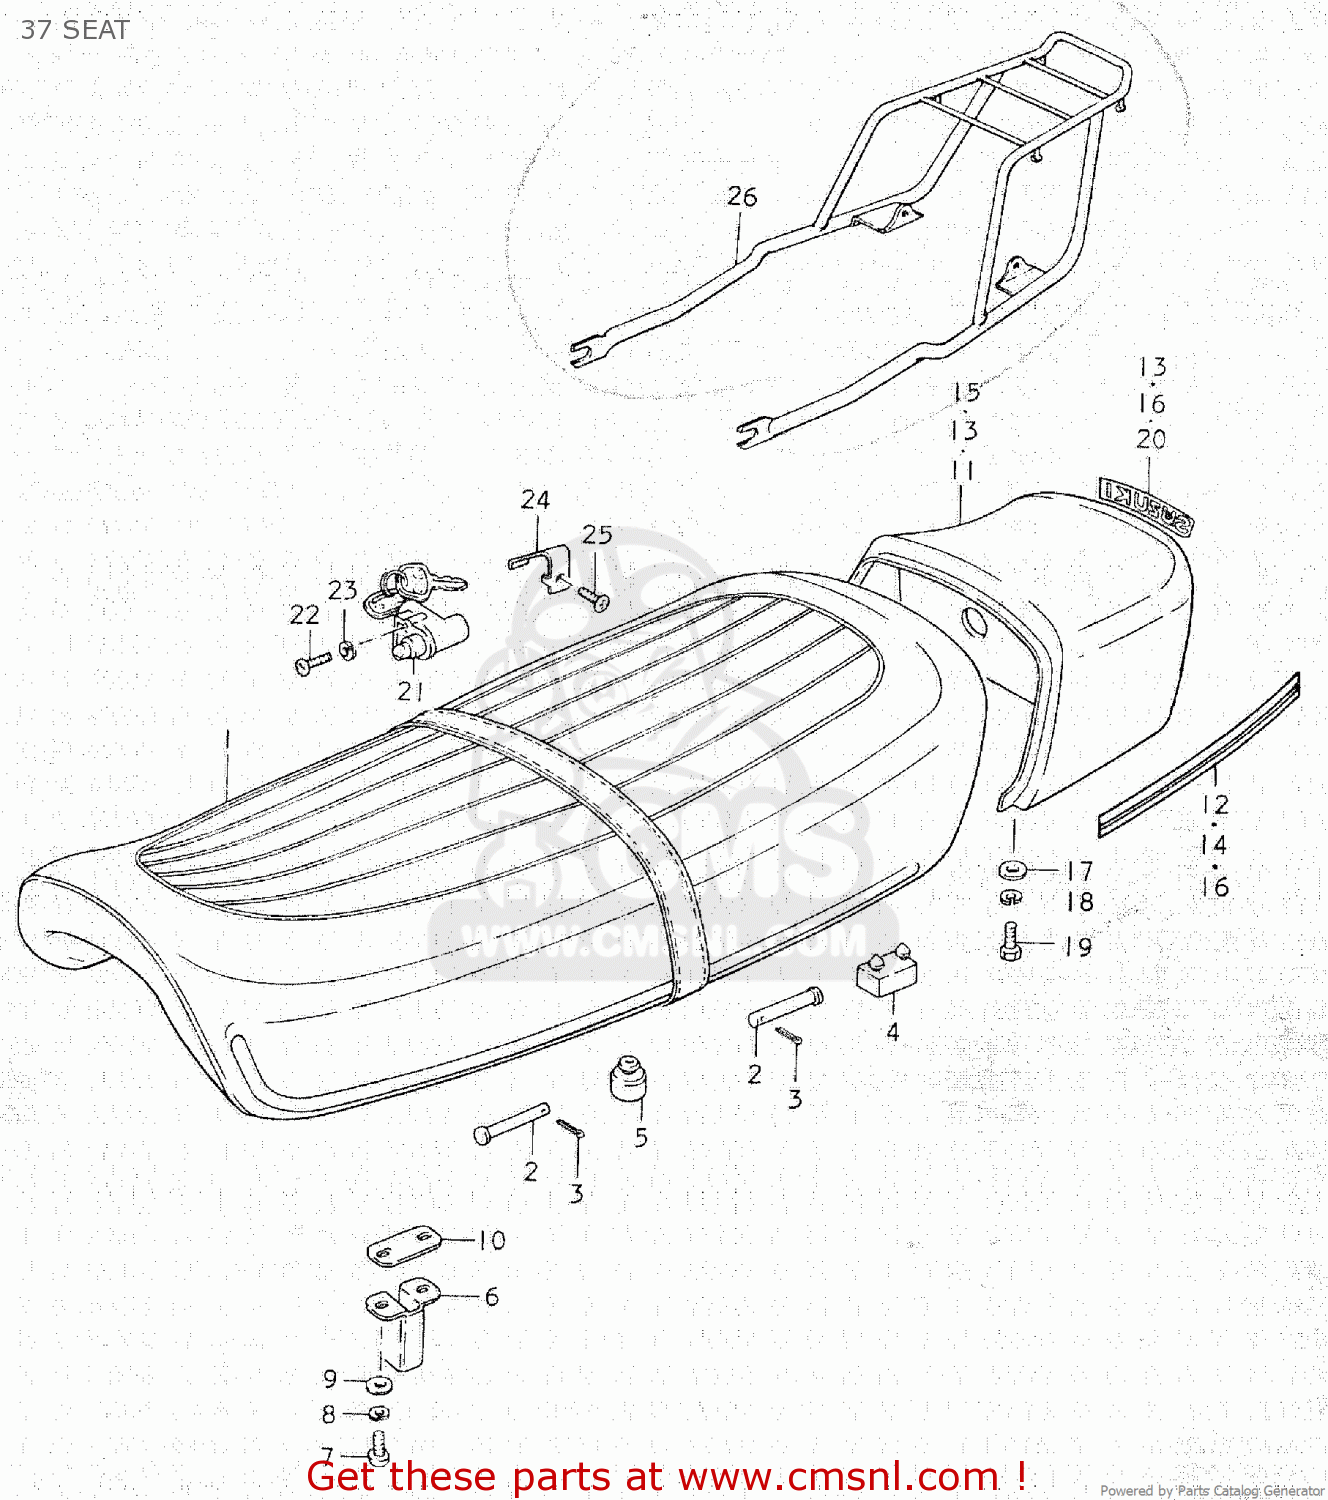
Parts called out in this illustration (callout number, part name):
1	SEAT ASSEMBLY
2	PIN
3	PIN
4	CUSHION
5	CUSHION
6	STRIKER,SEAT LOCK
7	BOLT
8	LOCK WASHER
9	WASHER
10	SHIM,SEAT LOCK STRIKER
11	COVER,SEAT TAIL
12	TAPE SET
13	COVER,SEAT TAIL
14	TAPE SET
15	COVER,SEAT TAIL
16	TAPE, STRIPING
17	WASHER
18	LOCK WASHER
19	BOLT, UPPER
20	EMBLEM
21	LOCK ASSEMBLY,SEAT
22	SCREW
23	LOCK WASHER
24	SPRING,HELMET HOLDER
25	SCREW
26	CARRIER
